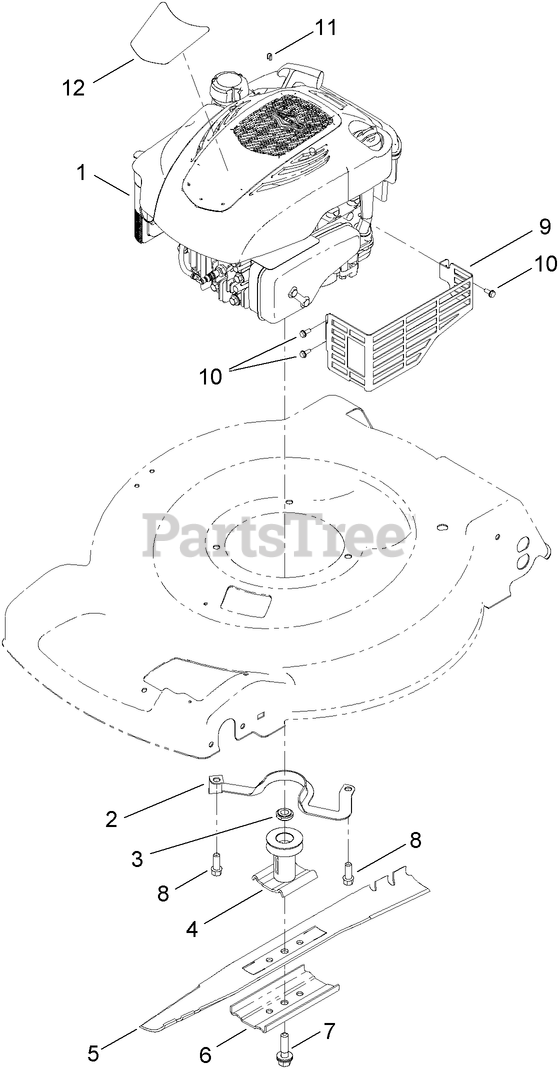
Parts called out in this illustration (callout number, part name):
2	GUIDE-BELT
3	SPACER-DRIVER
4	DRIVER-BLADE
6	SUPPORT-BLADE
8	SCREW-TAPTITE
9	SHIELD-MUFFLER
10	SCREW-TAPTITE
11	STOP-ROPE
12	DECAL-SHROUD
